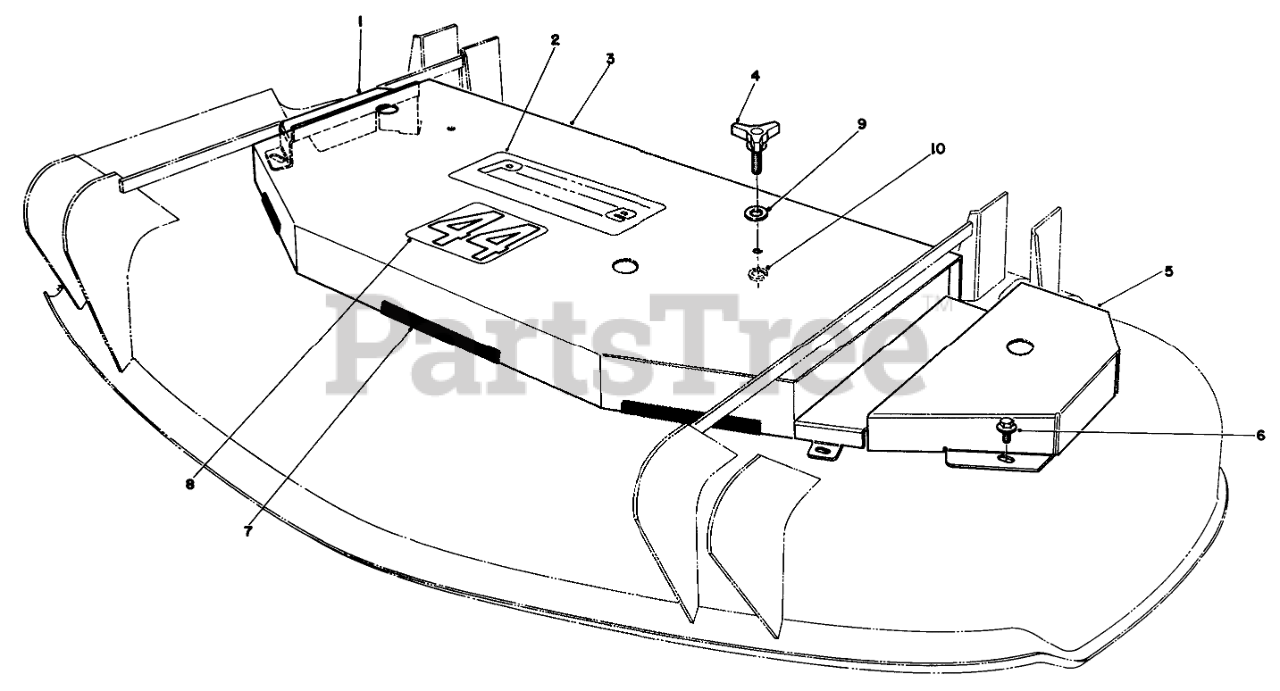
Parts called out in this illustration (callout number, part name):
1	Cover-RH
2	DECAL-PROLINE
3	Cover-Deck
5	Cover-LH
6	SCREW-HHFTF
7	TRIM-JIFFY
8	DECAL-44 INCH
9	WASHER-FLAT
10	RING-RETAINING
